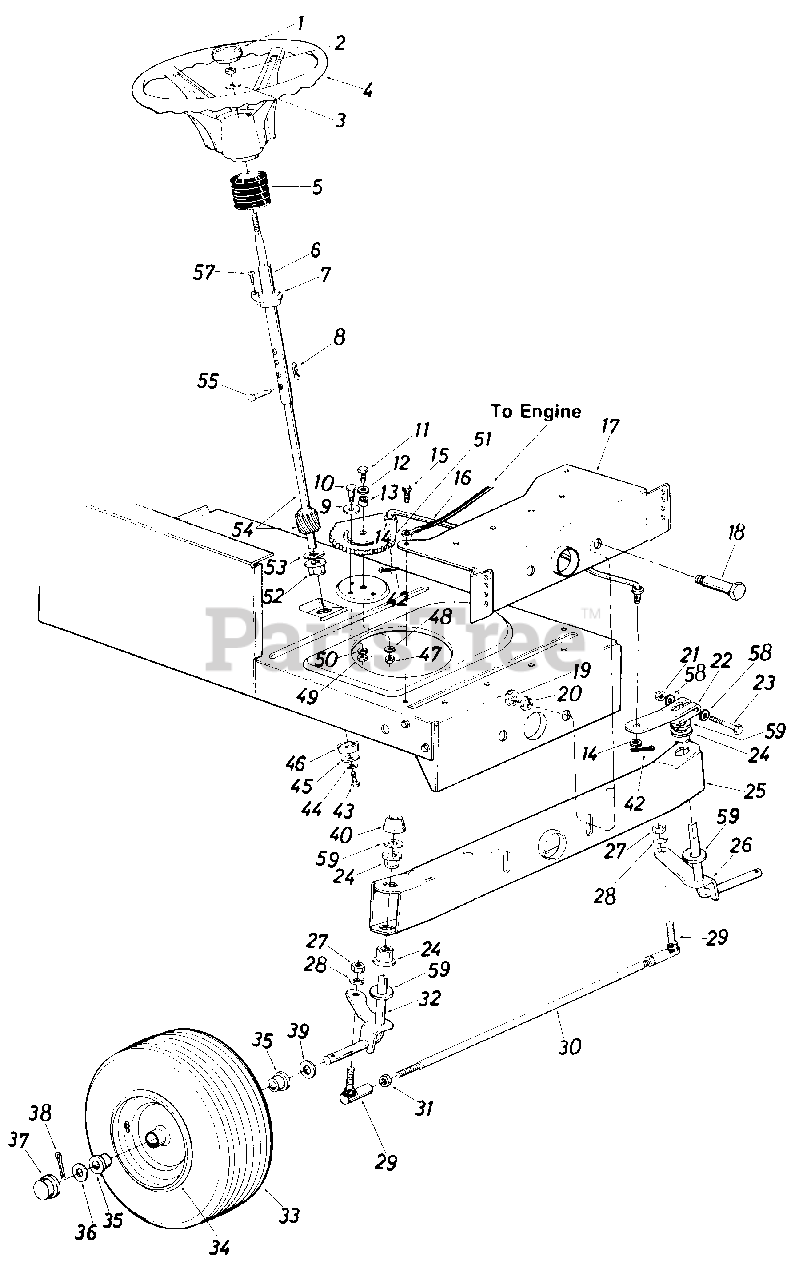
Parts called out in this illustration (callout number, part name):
1	Steering Wheel Cap
2	Hex Nut 5/16-18 Thd.
3	Belleville Wash. .345" I.D.
4	Steering Wheel 12" Dia.
5	Steering Bellow
6	Steering Column Ass'y.
7	Flange Bearing .890 I.D. x 1.36 O.D.
8	Internal Cotter Pin 1/4" Dia.
9	Fl-Wash. .438" I.D. x 1.37" O.D.
10	Shoulder Bolt .437" Dia. x .35 Lg. 5/16-18 Thd.
11	Hex Bolt 3/8-24 x 1.0" Lg. (Grade 5)
12	Fl-Wash. .38" I.D. x 1.0" O.D.
13	Spacer.380" I.D. x .625" O.D. x .227
14	Flat Washer .56 I.D. x 1.0 O.D.
15	Hex Wash. Hd. Self-Tap Scr.
16	Steering Drag Link
17	Front Pivot Brkt.
18	Shoulder Bolt .498" Dia. x 2.04 Lg. 3/8-16 Thd.
19	Hex Nut 3/8-16 Thd.
20	L-Wash. 3/8" I.D.
21	Hex Cent. L-Nut 5/16-24 Thd.
22	Steering Arm Front Axle
23	Hex Bolt 5/16-24 x 2.00" Lg. (Grade 5)
24	Hex Flg. Brg. .634 I.D.
26	Front Ax le Ass'y.-L.H.
27	Hex Nut 3/8-24 Thd.
28	L-Wash. 3/8" I.D.
29	Ball Joint 3/8-24 Thd.
30	Tie Rod
31	Hex Jam Nut 3/8-24 Thd.
32	Front Axle Ass'y.-R.H.
33	Wheel Ass'y. Comp.
34	Front Wheel Rim Only
35	Bearing
36	Fl-Wash. .635 I.D. x 1.59" O.D.
37	Front Wheel Hub Cap
38	Cotter Pin 118" Dia. x 1.25" Lg.
39	Fl-Wash. .635" I.D. x 1.20" O.D.
40	Push Cap 518" Dia. Rod
42	Cotter Pin 118" Dia. x 1.0" Lg.
43	Hex L-Bolt 5/16-18 x .62" Lg.*
44	L-Wash. 5/16" I.D.
45	Fl-Wash. .344" I.D. x 1.25" O.D.
46	Spacer (Plastic)
47	Hex Nut 3/8-24 Thd.
48	L-Wash. 3/8" I.D.
49	Hex Nut 5/16-18 Thd.
50	L-Wash. 5/16" I.D.
51	Steering Gear Segment
52	Hex Flg. Brg. .634 I.D.
53	Fl-Wash. (Hardened)
54	Steering Shaft Lower
55	Clevis Pin 1/4" Dia. x 1.00" Lg.
57	Oval Hd. Cr.-Sunk Scr. #10 x 5/8" Lg.
58	Bell-Wash.
59	Fl-Wash. (Hardened)
